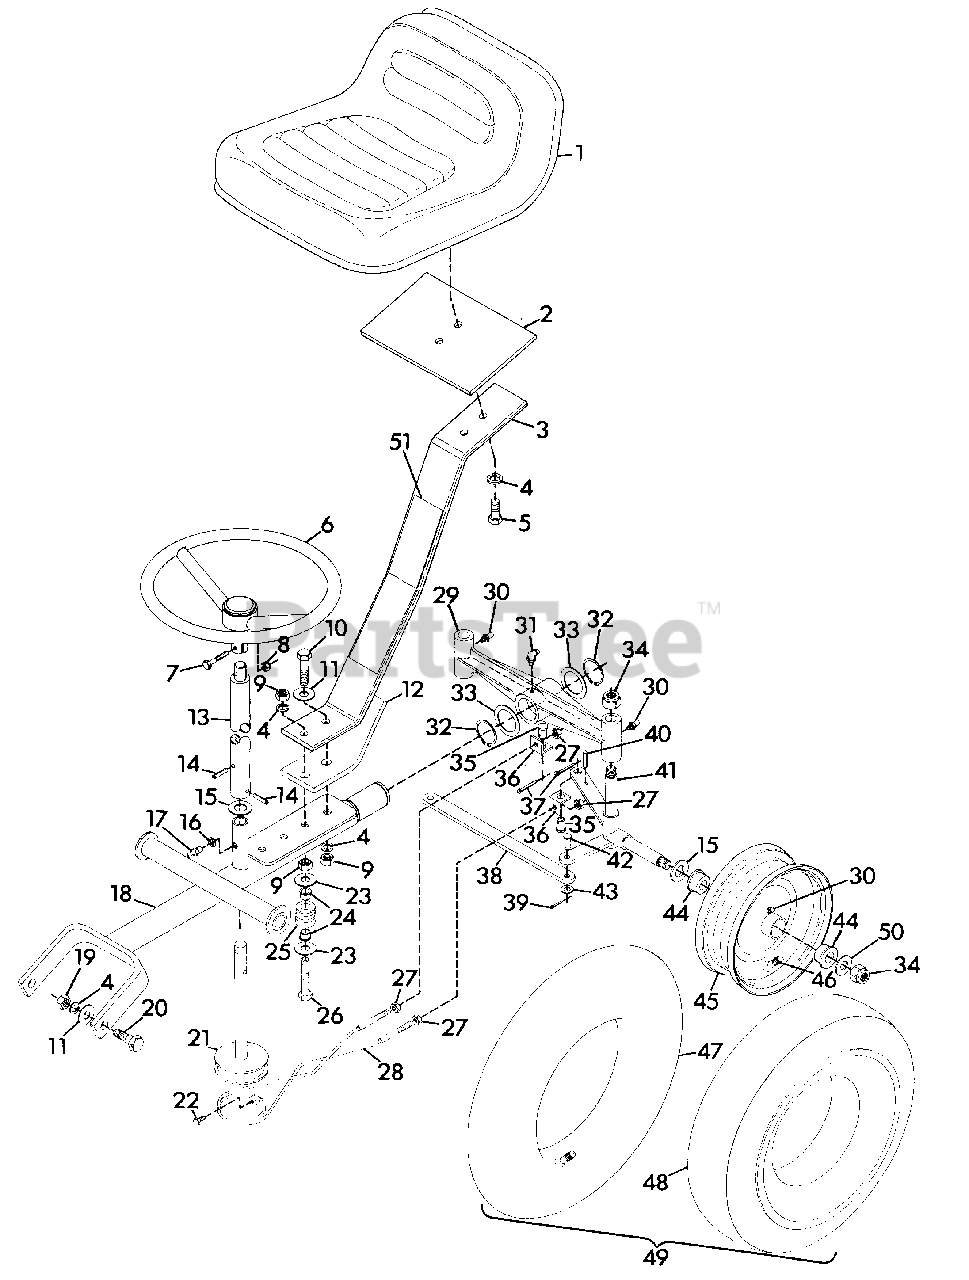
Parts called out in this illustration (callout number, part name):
1	SEAT, RIDER
2	PLATE
3	ASSEMBLY, SEAT SPRING AND DECAL
4	WASHER, LOCK 1/2-13 REG.
5	BOLT, HEX 1/2-13X1.25
6	WHEEL, STEERING
7	BOLT, HEX 3/8-16X1.375
8	NUT, LOCK 3/8-16
9	NUT, JAM 1/2-13 HEX
10	BOLT, HEX 1/2-13X3.50
11	WASHER, FLAT .563X1.375X.109
12	PLATE, REINFORCEMENT
13	COLUMN, STEERING
14	PIN, SPRING .25X1.125
15	WASHER, FLAT .812X1.496X.134
16	WASHER, LOCK 1/4 INTERNAL TOOTH
17	FITTING, LUBE 1/4-28
18	WELDMENT, CHASSIS SULKY
19	NUT, HEX 1/2-13
20	BOLT, HITCH
21	REEL, ASSEMBLY
22	BOLT, HEX 1/4-28X.50
23	WASHER, FLAT .531X1.000X.063
24	BUSHING, CABLE GUIDE PULLEY
25	PULLEY, CABLE GUIDE
26	BOLT, 1/2-13X5.0
27	NUT, HEX 5/16-18
28	CABLE, STEERING
29	BAR, CROSS
30	FITTING, LUBE 1/4-28
31	FITTING, LUBE 90 DEGREE
32	RING, RETAINING
33	WASHER
34	NUT, LOCK 5/8-18 L.T.
35	PIN, SWIVEL
36	BRACKET, SWIVEL
37	PIN, COTTER .125X1.25
38	BAR, TIE
39	PIN, COTTER .094X.75
40	PIN, SPRING .25X1.875
41	WELDMENT, AXLE L.H.
41	WELDMENT, AXLE R.H.
42	PIN, CLEVIS .375X.750
43	WASHER, FLAT .406X.812X.065
44	BUSHING, WHEEL
45	WHEEL, ASSEMBLY LESS TIRE/TUBE
46	ASSEMBLY, VALVE STEM
47	TUBE
48	TIRE
49	WHEEL, SULKY ASSEMBLY COMPLETE(INCLUDES ITEM NOS. 30,44,45,46,48)
50	WASHER, FLAT .656X1.312X.095
51	DECAL, WARNING
